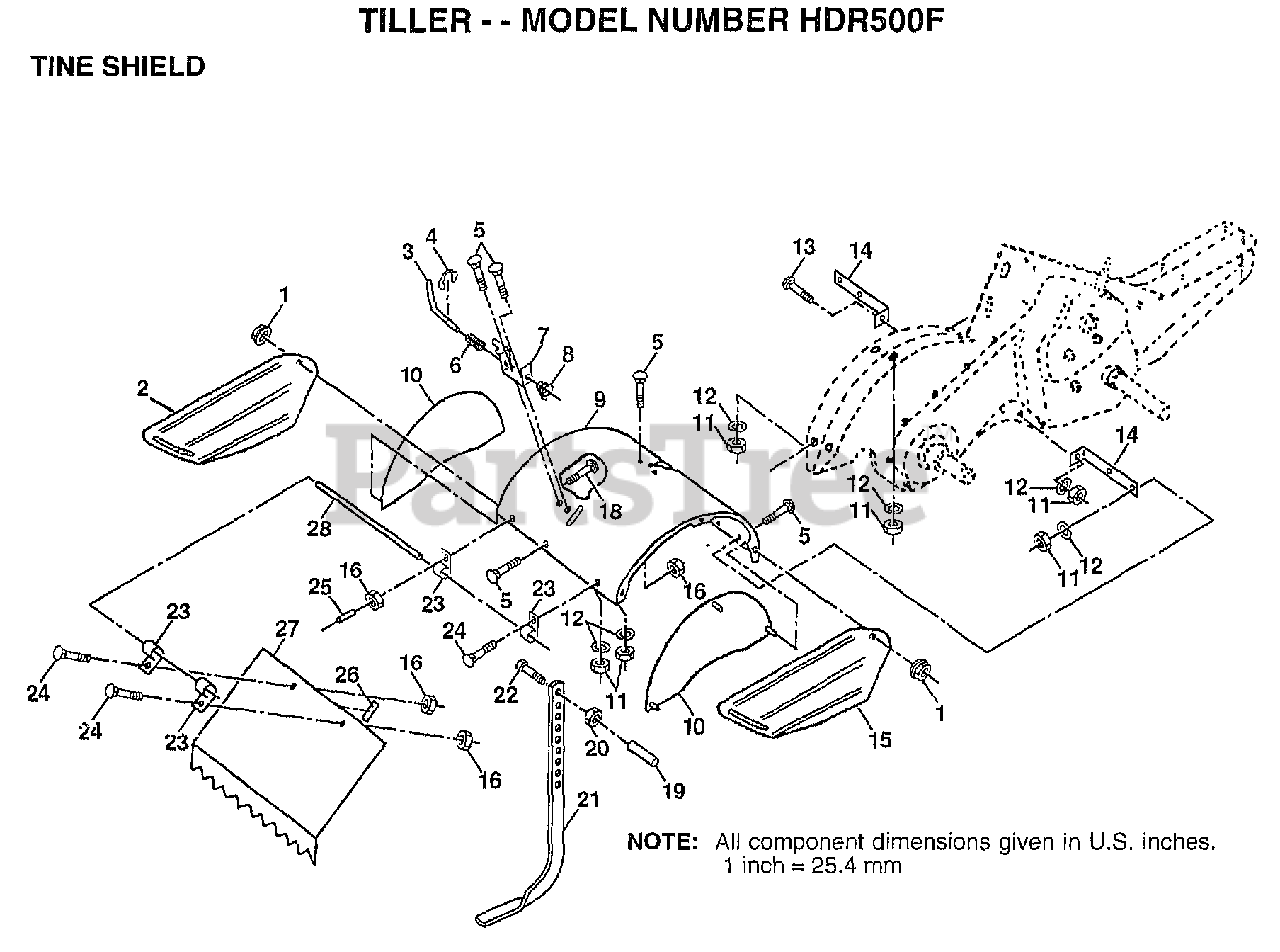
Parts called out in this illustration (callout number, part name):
1	NUT
2	SHLD.SIDE.OUTER.L
3	STAKE PIN TI
4	KLIP RING TI
5	BOLT
6	SPRING TI
7	LATCH BRACKET TI
8	SPRING CRT
9	SHIELD TINE
10	SHIELD SIDE
11	NUT.HEX.5/16-18
12	LOCKWASHER
13	BOLT
14	BRKT SHIELD TINE
15	SHLD.SIDE.OUTER.R
16	NUT
18	BOLT
19	GRIP CRT
20	NUT.HEX.3/8-16UNC
22	BOLT
23	HINGE CRT
24	BOLT
25	VINYL CAP TI
26	PAD IDLER TI
27	"SHIELD,LEVEL"
28	PIN HINGE
